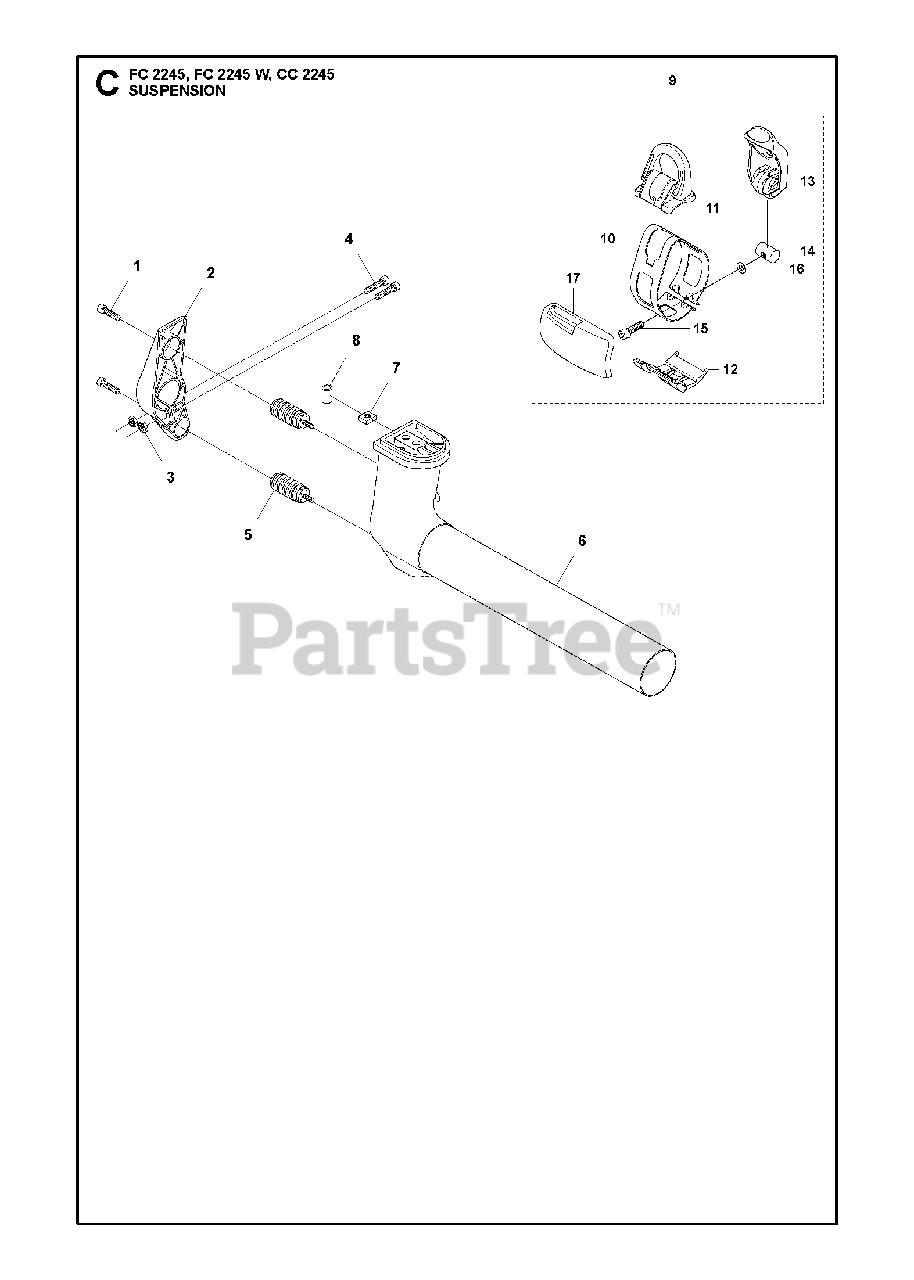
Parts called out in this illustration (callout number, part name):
10	BRACKET
14	NUT
15	SCREW
16	WASHER 5.3X12
